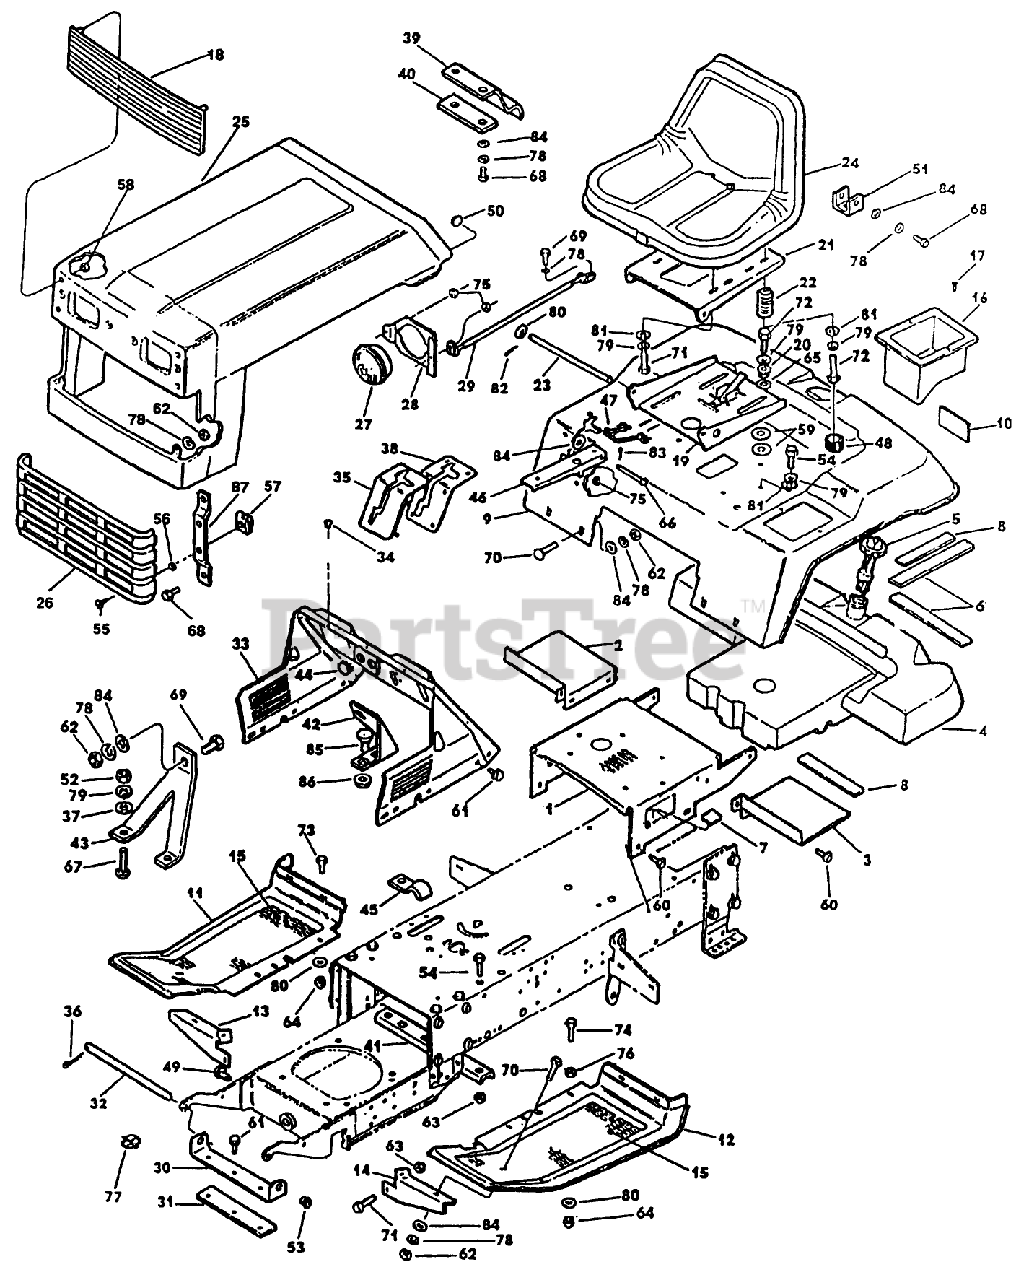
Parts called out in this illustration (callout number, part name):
4	TANK - FUEL
5	GUAGE ASSEMBLY-FUE
8	PAD - FUEL TANK
10	REFLECTOR
11	FOOTREST - RH *G
17	Rivet
19	SEAT SUPPORT AY
21	PIVOT AY - SEAT *B
23	PIN
24	SEAT
25	HOOD GRILLE WLDMT *G
26	INSERT - GRILLE
32	ROD - HOOD PIVOT
43	BRACKET-SUPPORT
46	LATCH - SEAT PAN *B
48	CAP-PROTECTOR
52	NUT SS
53	BEARING-NYLINER
55	FASTENER-1/4 TURN
59	WASHER-PLASTIC
62	NUT
63	NUT
64	NUT-LOCKING
66	PIN
67	BOLT - CARRIAGE
68	SCREW-HH
69	SCREW
71	SCREW - HEX
72	SCREW
76	NUT
77	CLIP-RETAINER, WIRE
80	WASHER
